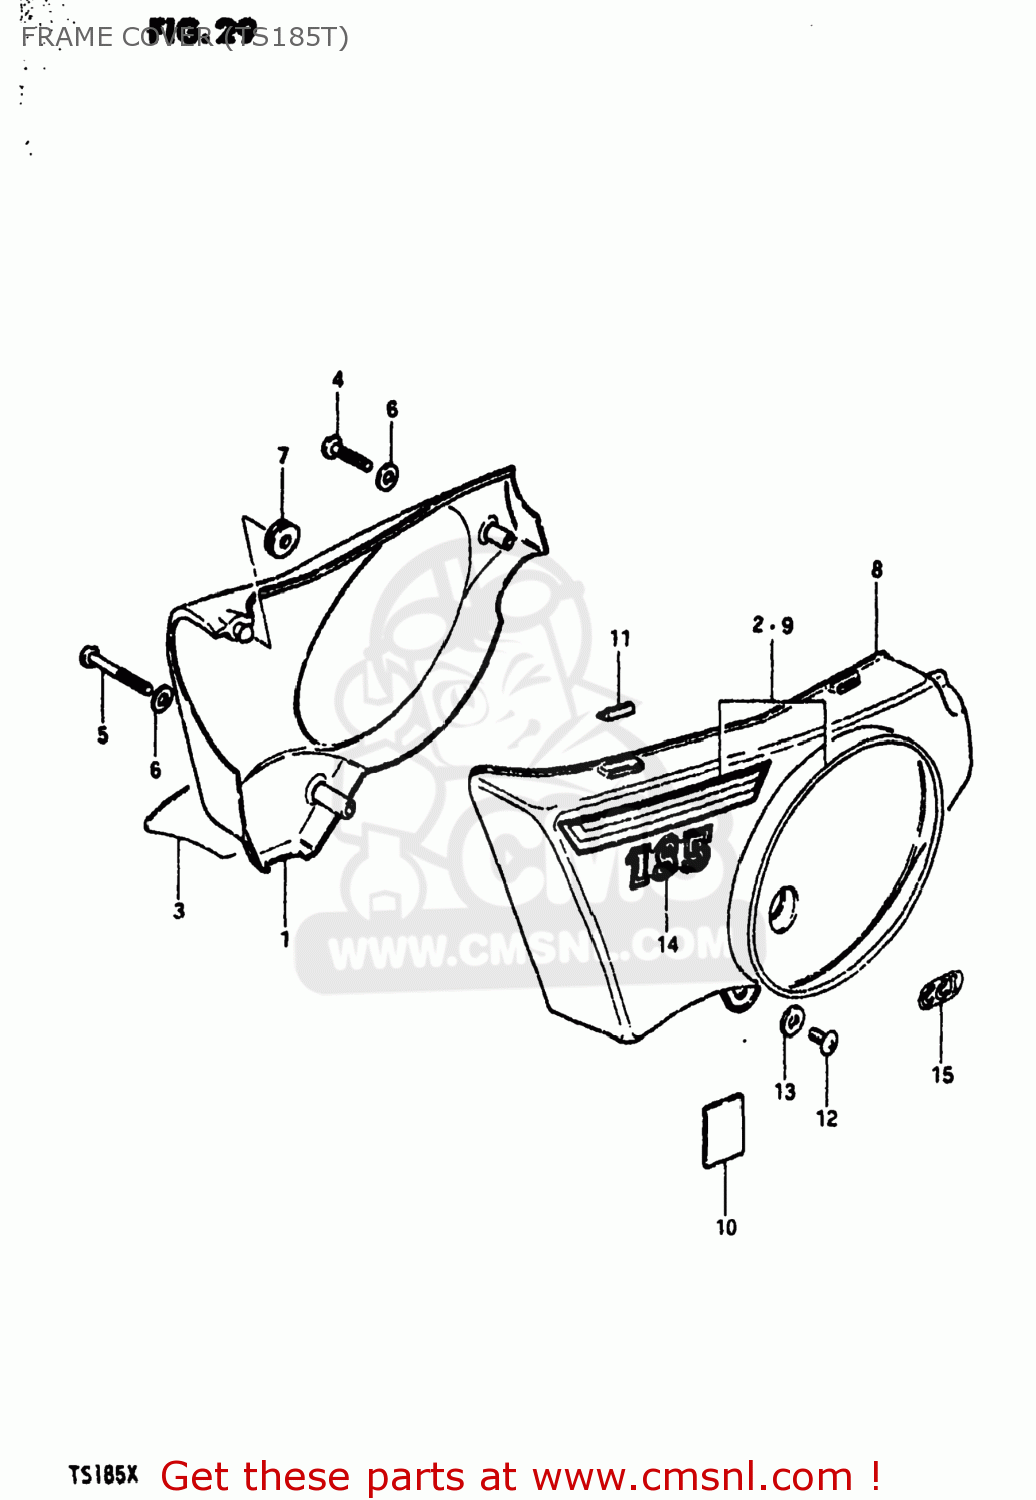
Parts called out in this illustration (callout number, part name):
1	COVER,FRAME,RIGHT
2	TAPE SET,FRAME COVER
3	EMBLEM,FRAME COVER,RIGHT
4	SCREW
5	SCREW
6	WASHER
7	CUSHION
8	COVER,FRAME,LEFT
9	TAPE SET,FRAME COVER
10	PROTECTOR(170X95X3.0)
11	CUSHION,FRAME COVER
12	SCREW 6X12
13	WASHER
14	EMBLEM
15	EMBLEM,CCIS
